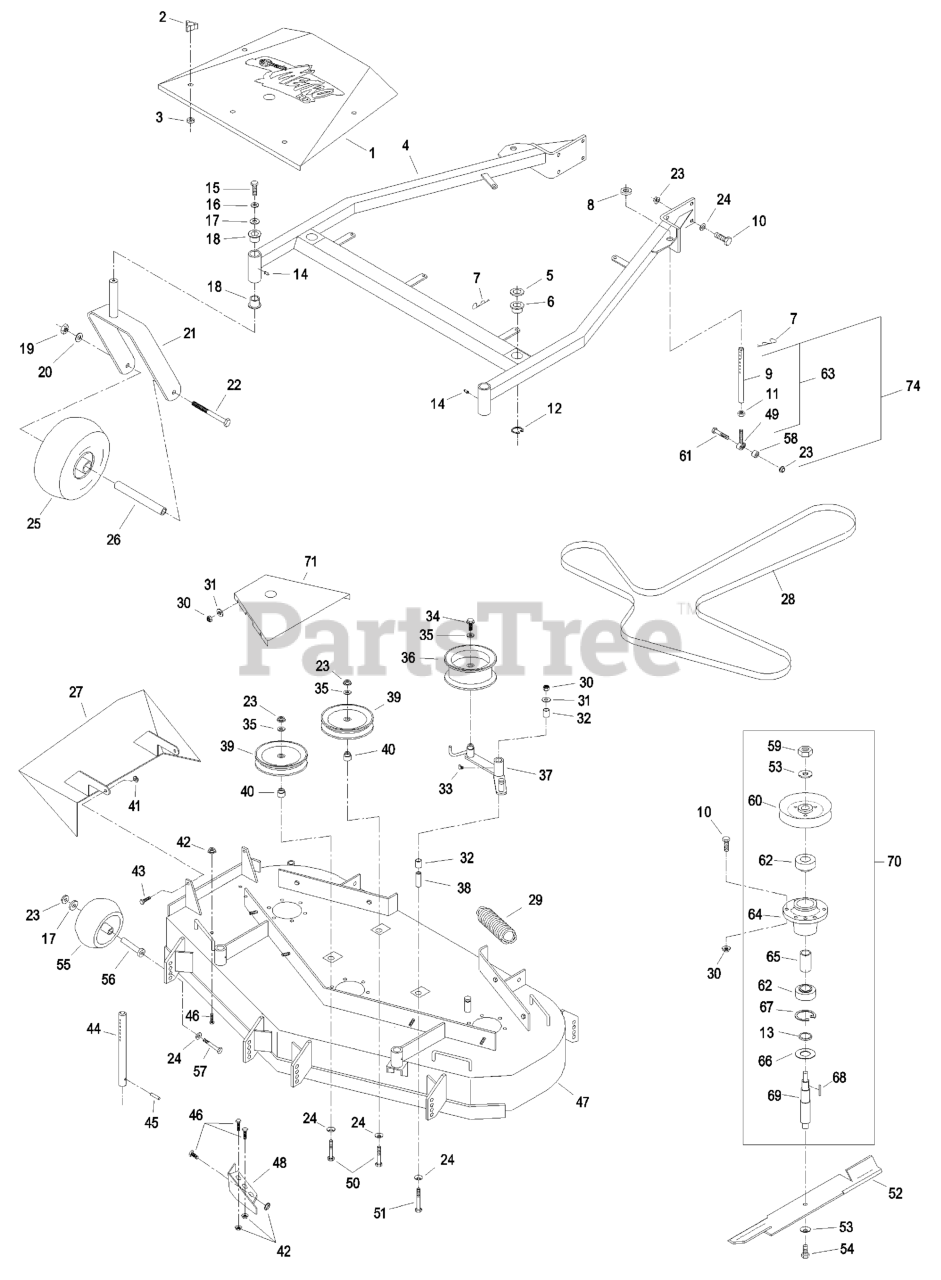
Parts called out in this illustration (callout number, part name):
1	SHIELD W/DECAL,MHP52
2	KNOB-3 PRONG
4	SUPPORT,DECK W/BUSHINGS
5	SPACER-DECK SUPPORT
6	BUSHING-DECK
7	PIN,HAIR COTTER
9	LINK,SUPPORT
13	SPACER-PULLEY/BEARING
18	BEARING-FLANGED
27	WLD,CHUTE DISCHARGE
28	BELT,DECK DRIVE
32	SLEEVE-BEARING
38	BUSHING-PIVOT, IDLER
39	PULLEY-IDLER
40	BUSHING-IDLER
44	ROD,DECK SUPPORT
47	ASM,DECK W/DECALS TTHP52
48	WLD,BAFFLE DISCHARGE
49	BALLJOINT
51	SCREW-HH
53	WASHER-SPRING
55	ROLLER-SCALP, ANTI
56	BUSHING-ROLLER
60	SHEAVE,W/HUB 5.72
62	BEARING
65	SPACER-BEARING
66	GUARD-BEARING, BOTTOM
68	KEY-RECTANGLE
69	SHAFT,SPINDLE
70	HOUSING,CUTTER COMPLETE
